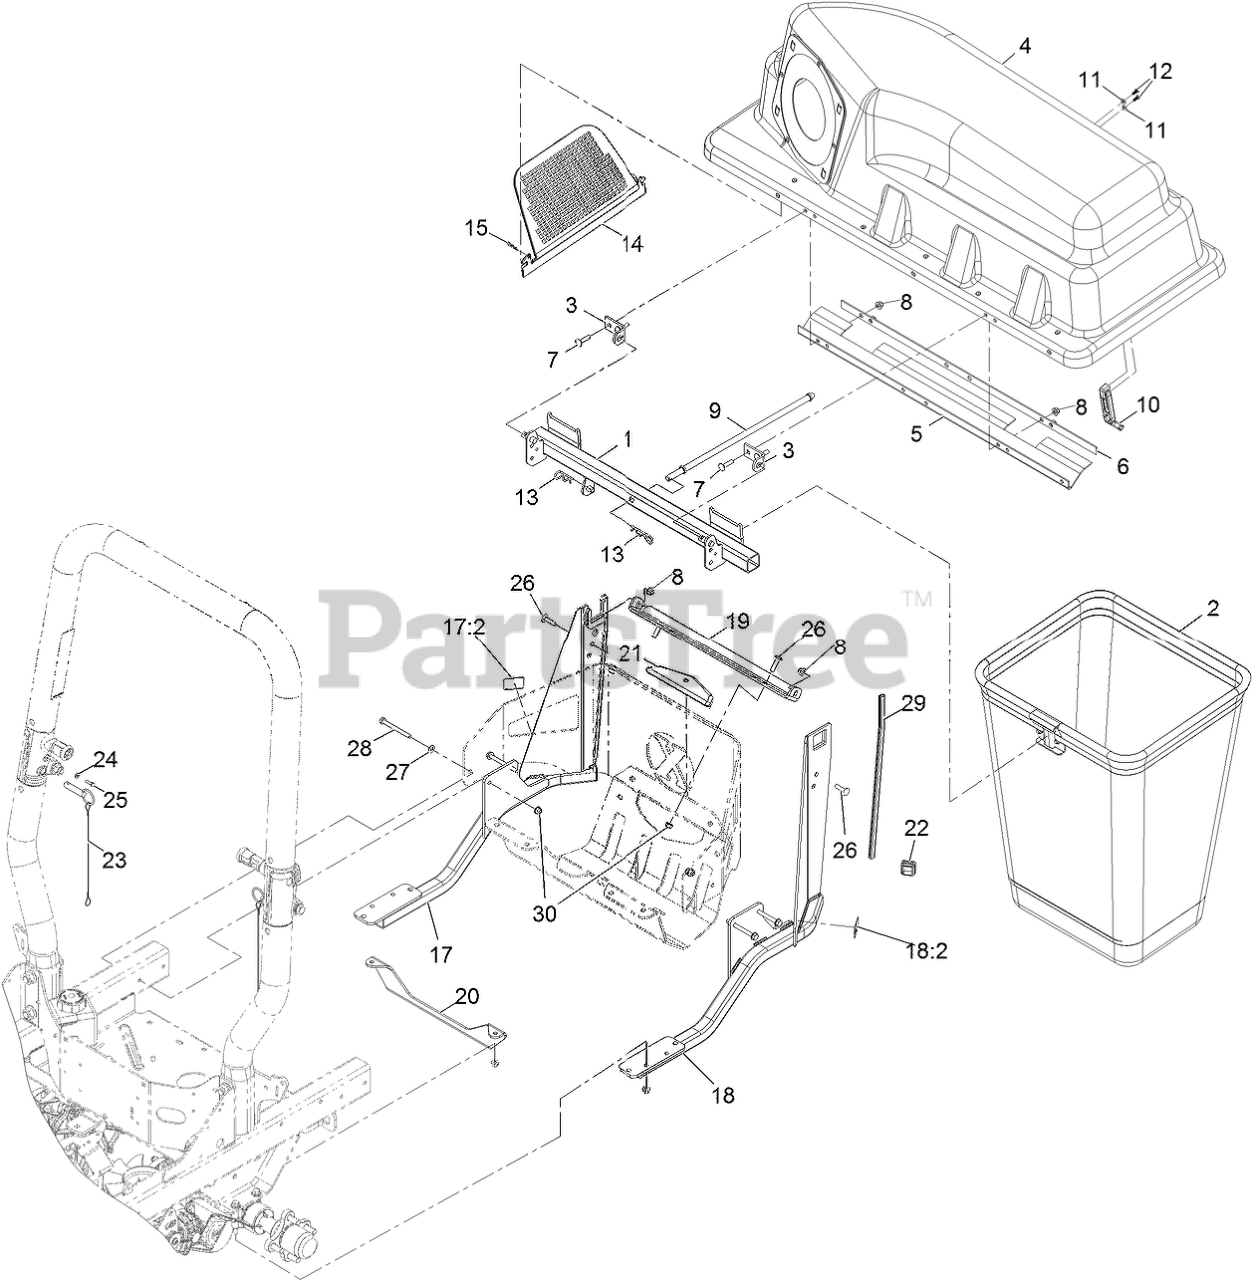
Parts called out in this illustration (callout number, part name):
1	FRAME PIVOT ASM
2	BAG AND FRAME ASM
3	BRACKET-PIVOT, HOPPER
4	BAGGER HOOD ASM
6	PLATE-BACKING
7	Bolt-Carriage 5/16-18 X 1 1/4
8	NUT-HF, NI
9	ROD-HOLD DOWN, HOOD
10	LATCH-RUBBER
11	WASHER-FLAT
12	SCREW-PLASTITE
13	PIN-HAIR
14	SCREEN-BAGGER
17	RH BAGGER SUPPORT ASM
17:2	DECAL-WARNING
18	LH BAGGER SUPPORT ASM
18:2	DECAL-WARNING
19	ANGLE-SUPPORT
20	SUPPORT-TRANSMISSION
21	COVER-HITCH
23	HITCH PIN ASM
24	WASHER-FLAT
26	SCREW-CARR
27	WASHER-PLAIN
28	SCREW-HH
29	Strip-Trim
30	NUT-HF, NI
